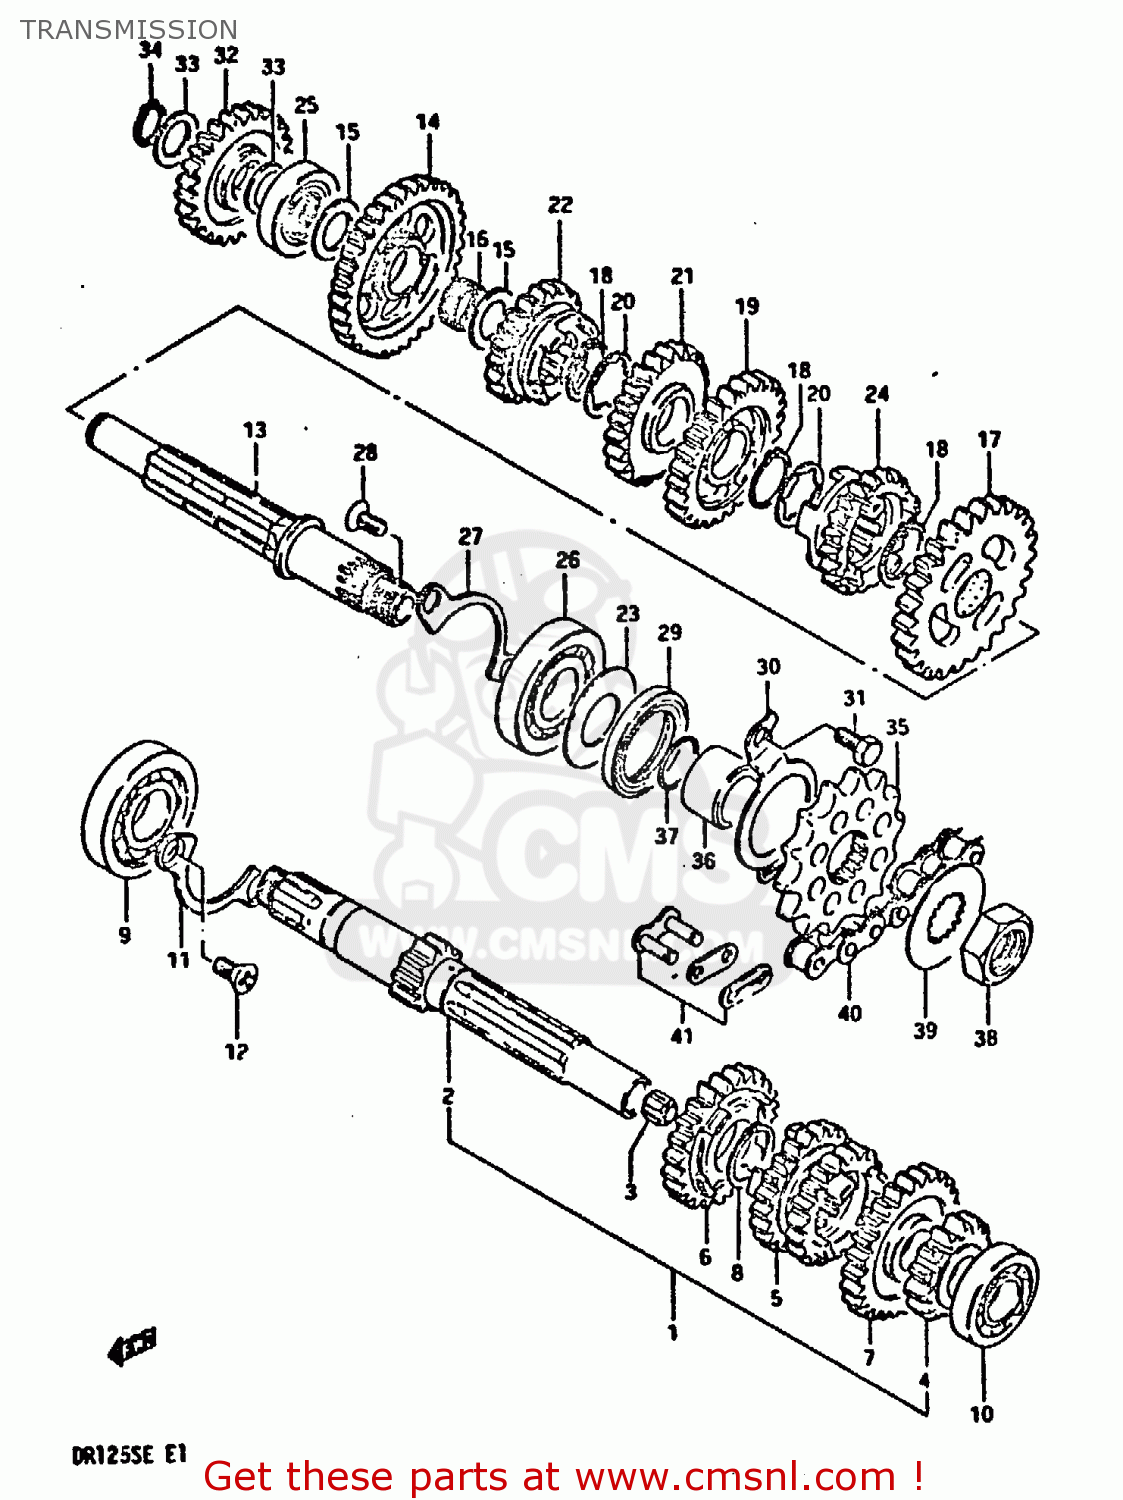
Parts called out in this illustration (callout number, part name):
1	SHAFT,COUNTER
2	SHAFT,COUNTER
3	BUSH
4	GEAR,SECOND DRIVE
5	GEAR,THIRD & FOURTH DRIVE,N
6	GEAR,FIFTH DRIVE
7	GEAR,SIXTH DRIVE
8	CIRCLIP
9	BEARING
10	BEARING, LH
11	RETAINER,DRIVE SHAFT BEARING
12	SCREW
13	SHAFT,DRIVE
14	GEAR,FIRST DRIVEN
15	WASHER
16	BEARING(15X19X7.8)
17	GEAR,SECOND DRIVEN
18	CIRCLIP
19	GEAR,THIRD DRIVEN
20	WASHER,LOCK
21	GEAR,FOURTH DRIVEN
22	GEAR,FIFTH DRIVEN
23	WASHER,OIL SEALING
24	GEAR,SIXTH DRIVEN
25	BEARING(15X33X12)
26	BEARING
27	RETAINER,DRIVE SHAFT BEARING
28	SCREW
29	SEAL,OIL(27X40X6)
30	PLATE,DRIVESHAFT OIL
31	BOLT
32	GEAR,KICK STARTER IDLE(NT:26)
33	WASHER
34	CIRCLIP,15MM
35	SPROCKET,ENGINE
36	SPACER
37	O RING(D:2.4,ID:19)
38	NUT
39	WASHER,LOCK
40	CHAIN ASSEMBLY,DRIVE
41	JOINT SET,CHAIN
